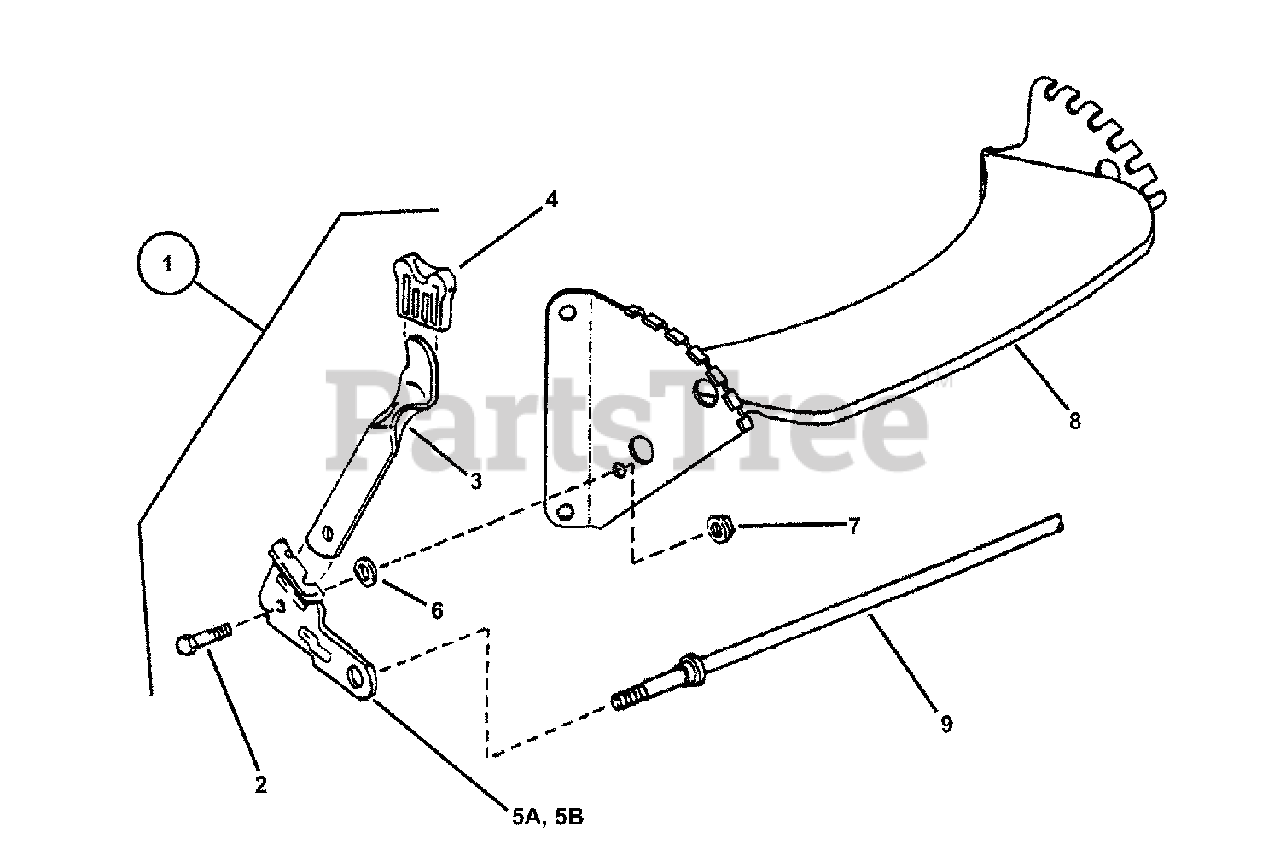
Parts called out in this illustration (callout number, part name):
1	ASSEMBLY, Right Wheel Arm
2	BOLT, 5/16-18 Hex Washer Face Shoulder
3	LATCH, Height
4	GRIP, Height Latch
5A	WHEEL ARM, R.H. Front (Round Hole)
6	RETAINER, 5/16" Bolt (Black)
7	NUT, 5/16-18 Hex Flange Lock GR5
8	WELDMENT, Front Wheel Bracket
9	AXLE, 21"
